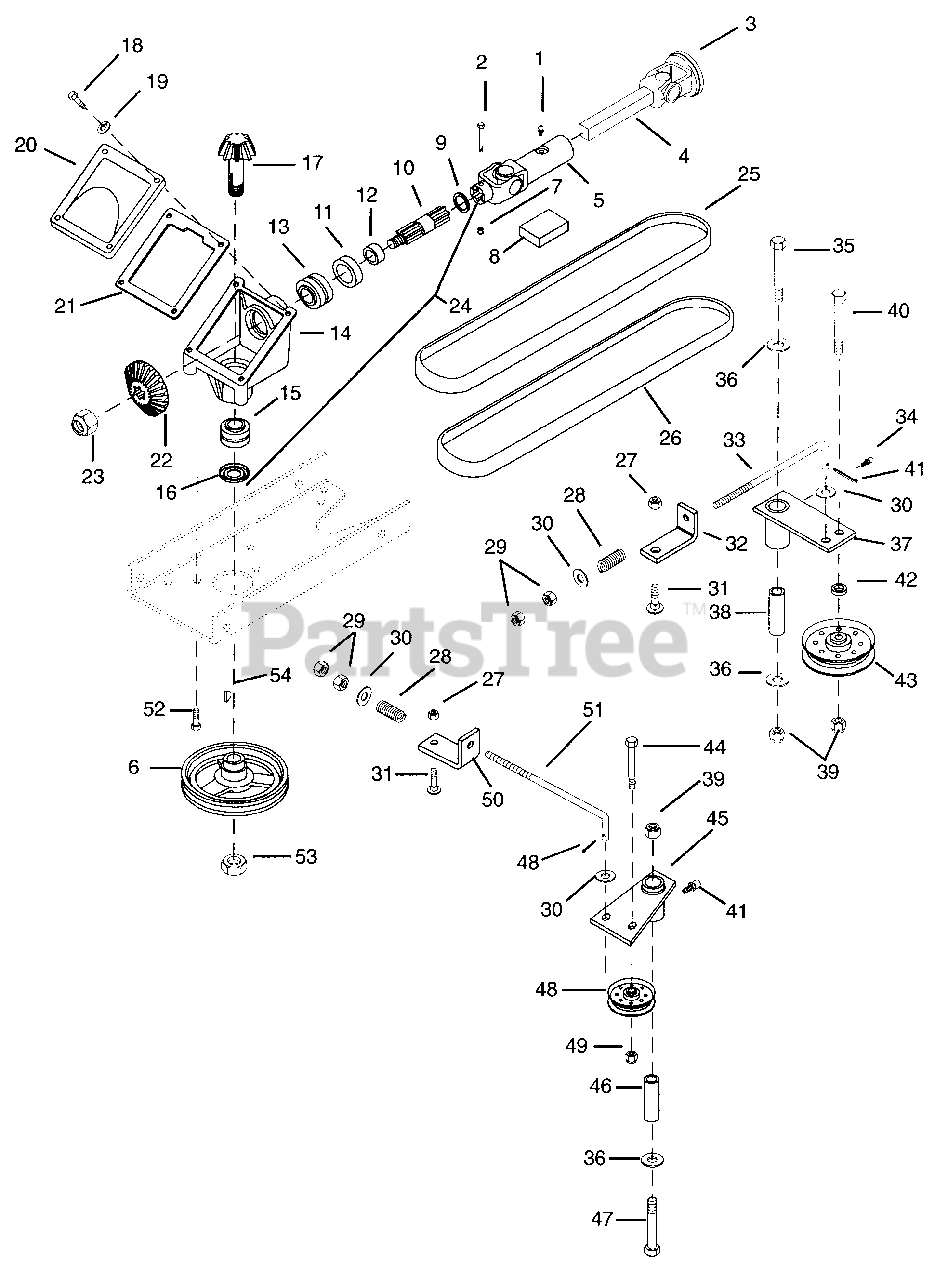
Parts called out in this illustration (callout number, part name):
1	Fitting-Lube .25-28 x .256
2	Bolt-Hex .25-20 x 2.25
3	Q.D. Yoke
4	Shaft-Prop Square Bar
5	Joint-U Female End
6	Pulley-Gearbox
7	Nut-Locking-Nylon .250-20 Grade 2
8	Kit-Repair U-Joint
9	Ring-Retaining 1.106 x .95
10	Shaft
11	Seal 1.250 x 1.983 x .250
12	Bushing Flange 1.00 x 1.25 x 1.25
13	Bearing-Assembly 1.000 x 1.980 x 1.243
14	Casting-Gear Box
15	Bearing-Assembly .75 x 1.781 x 1.499
16	Seal 1.250 x 1.691 x .310
17	Shaft-Pinion Gear
18	Bolt-Hex .25-20 x .50 Grade 5
19	Washer-Lock .250 Reg.
20	Cover-Gear Housing
21	Gasket-Gear Housing
22	Gear-Bevel
23	Nut-Locking-Nylon .75-10 Grade 2
24	Assembly-Drive 50" Mower
25	V-Belt A-Section 58.56 x .516
26	V-Belt 5L Section 70.375 x .438 x .660
27	Nut-Locking-Nylon .375-16 Grade 2
28	Spring-Compression .125 x .78 x 1.00
29	Nut-Hex .375-24 Grade 2
30	Washer-Flat-Steel .406 x .812 x .065
31	Bolt-Hex .375-16 x 1.00 Grade 5
32	Support-Spring "B"
33	Rod-Idler 50 In. Mower
34	Pin-Cotter .06 x 1.0
35	Bolt-Hex .50-13 x 3.75
36	Washer-Flat-Steel .500 x 1.250 x .083
37	Weldment-Idler Pivot "B"
38	Spacer .505 x .855 x 2.50
39	Nut-Locking-Nylon .50-13 Grade 5
40	Bolt-Hex .50-13 x 2.00 Grade 5
41	Fitting-Lube .25-28 x .46
42	Spacer .516 x .875 x .300
43	Idler-Flat-Pulley 6.75 x .510
44	Bolt-Hex .38-16 x 1.75 Grade 5
45	Weldment, Idler Pivot "A"
46	Spacer .562 x .855 x 2.18
47	Bolt-Round Head Square Neck .50-16 x 3.50
48	Pulley-Idler 4.50 x .380
49	Nut-Lock .375-16 Grade A
50	Support-Spring "A"
51	Rod-Idler 40 In. Mower
52	Bolt-Hex .50-13 x 1 Grade 5
53	Nut-Hex-Jam .750-10
54	Key-Woodruff .19 x .63
